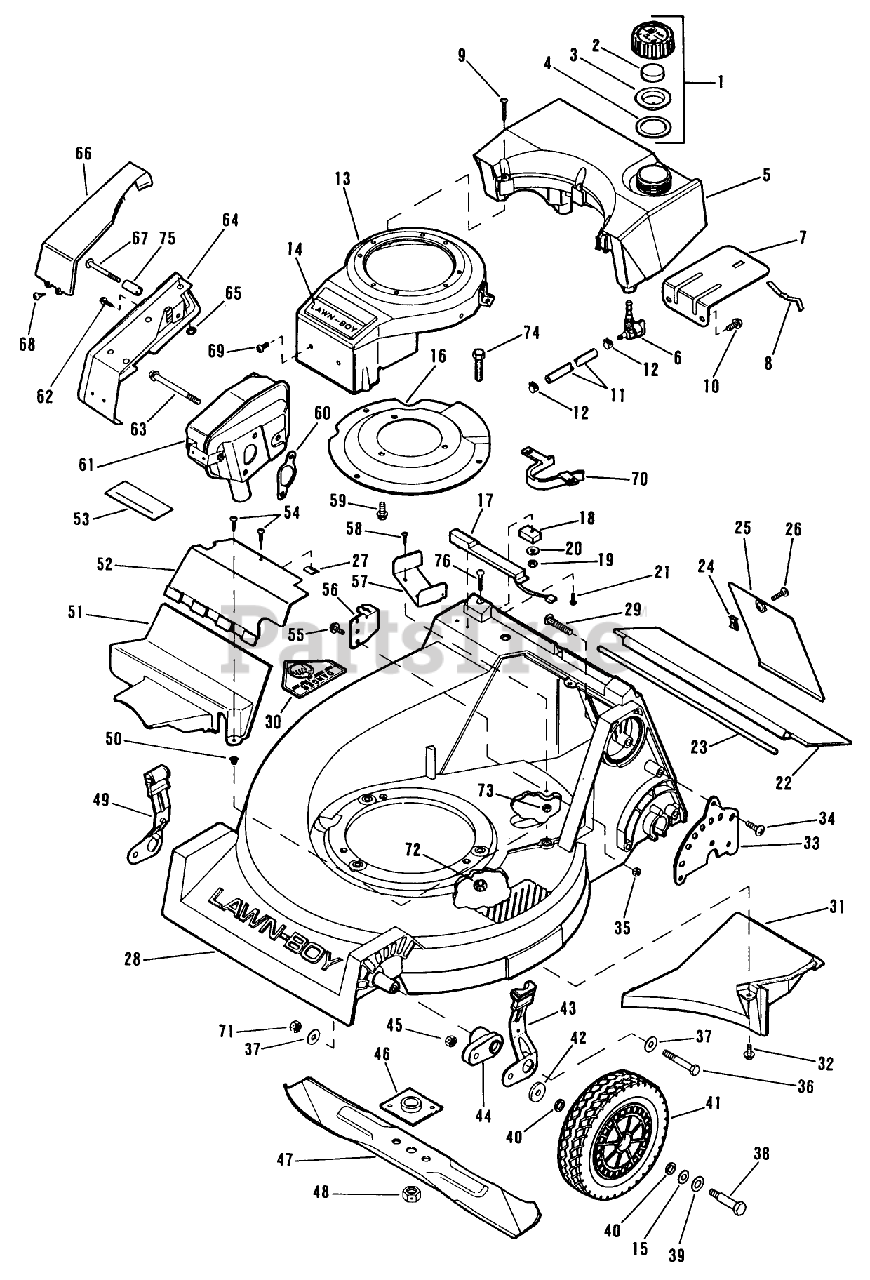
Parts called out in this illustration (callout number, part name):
1	CAP AY - F/OIL SM
2	BAFFLE - FOAM SM
4	GASKET-FUELCAP SM
6	DISC/LB SER.BUL.#6
7	DISC. LB SER.BUL.#6
8	SPRING
9	DISC.LB SER.BUL.#6
11	GAS LINE SM
12	HOSE CLAMP SM
14	APPLIQUE SM
15	WASHER
16	PLATE SM
17	SWITCH AY DELTA
24	SPEED NUT LARSON
25	DOOR-ACCESS ELECT.
26	SCREW-CROSS RECESS
27	NUT-SPEED
31	CHUTE BAFFLE NYL
33	PLATE HGT CMS
34	SCREW-BHTF
35	LOCKNUT E
37	WASHER-PLAIN
38	BOLT WHEEL QUAL
39	SPACER
40	WASHER
41	WHEEL&TIRE 8" TRI
42	WASHER
43	KNOB & SPRING CMS
44	ARM HGT ADJ *BLACK
45	NUT-JAM, LOCKING
46	PLATE AND COLLAR ASM
48	NUT-BLADE
49	KNOB & SPRING CMS
50	NUT-CLIP
54	SCREW S
57	BELT GUIDELB
60	GASKET - EXH SM
62	SCREW S
63	SCREW-SEMS
64	MUFFLER GUARD AY
65	NUT-PUSH
66	COVER MUFFLER CP
67	SCREW SM
68	SCREW SM
71	LOCKNUT
72	NUT-LOCK F
73	NUT C/LOCK E
74	SCREW-HH
75	SPACER S
